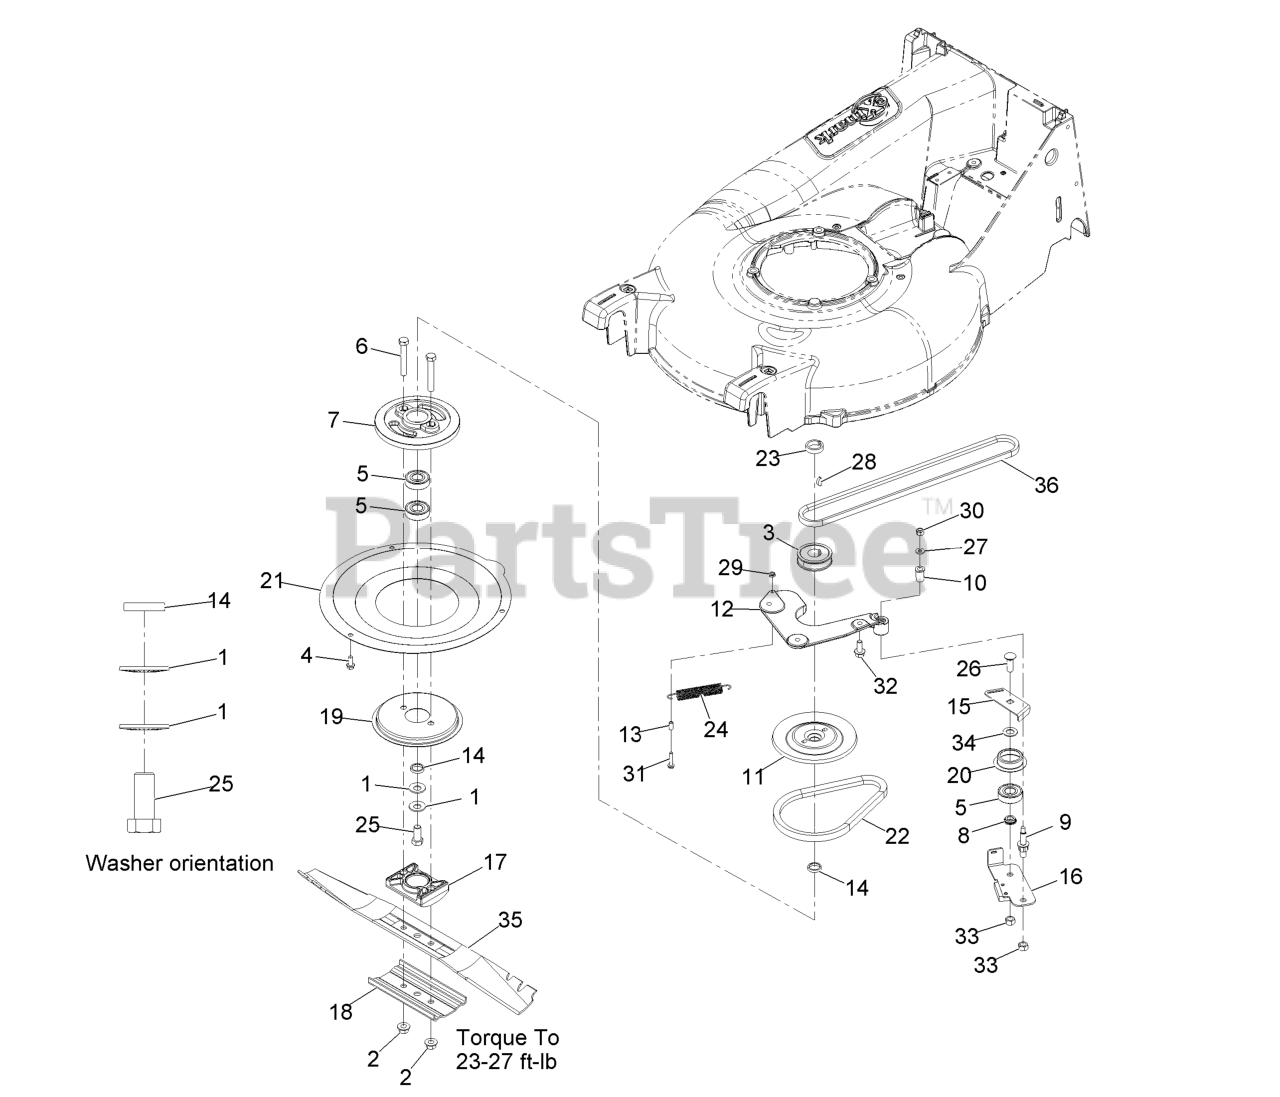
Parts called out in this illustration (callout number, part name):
1	WASHER-SPRING
2	Nut-Hex 3/8-24 Lock
3	PULLEY-DRIVER
4	SCREW-HWH
6	SCREW-HH
8	SPACER-BEARING
9	BOLT-SHOULDER
10	BUSHING
11	Pulley- Driver, Upper
12	PLATE-MOUNTING, BBC
13	SPACER-BBC
14	SPACER-PLATE, BBC
15	PLATE-GUIDE
17	SUPPORT-BLADE
18	SUPPORT-BLADE
19	DISC
20	RETAINER-BELT
21	COVER-BBC
22	BELT
23	SPACER-PULLEY
24	SPRING-EXTENSION
25	SCREW-HH
26	SCREW-CARR
27	WASHER-FLAT
28	KEY-WOODRUFF
29	NUT-LOCK, NI
30	NUT-LOCK, NI
31	SCREW-TAP
32	SCREW-HHF
33	LOCKNUT
34	SPACER
36	BELT,3L P21 DRIVE
